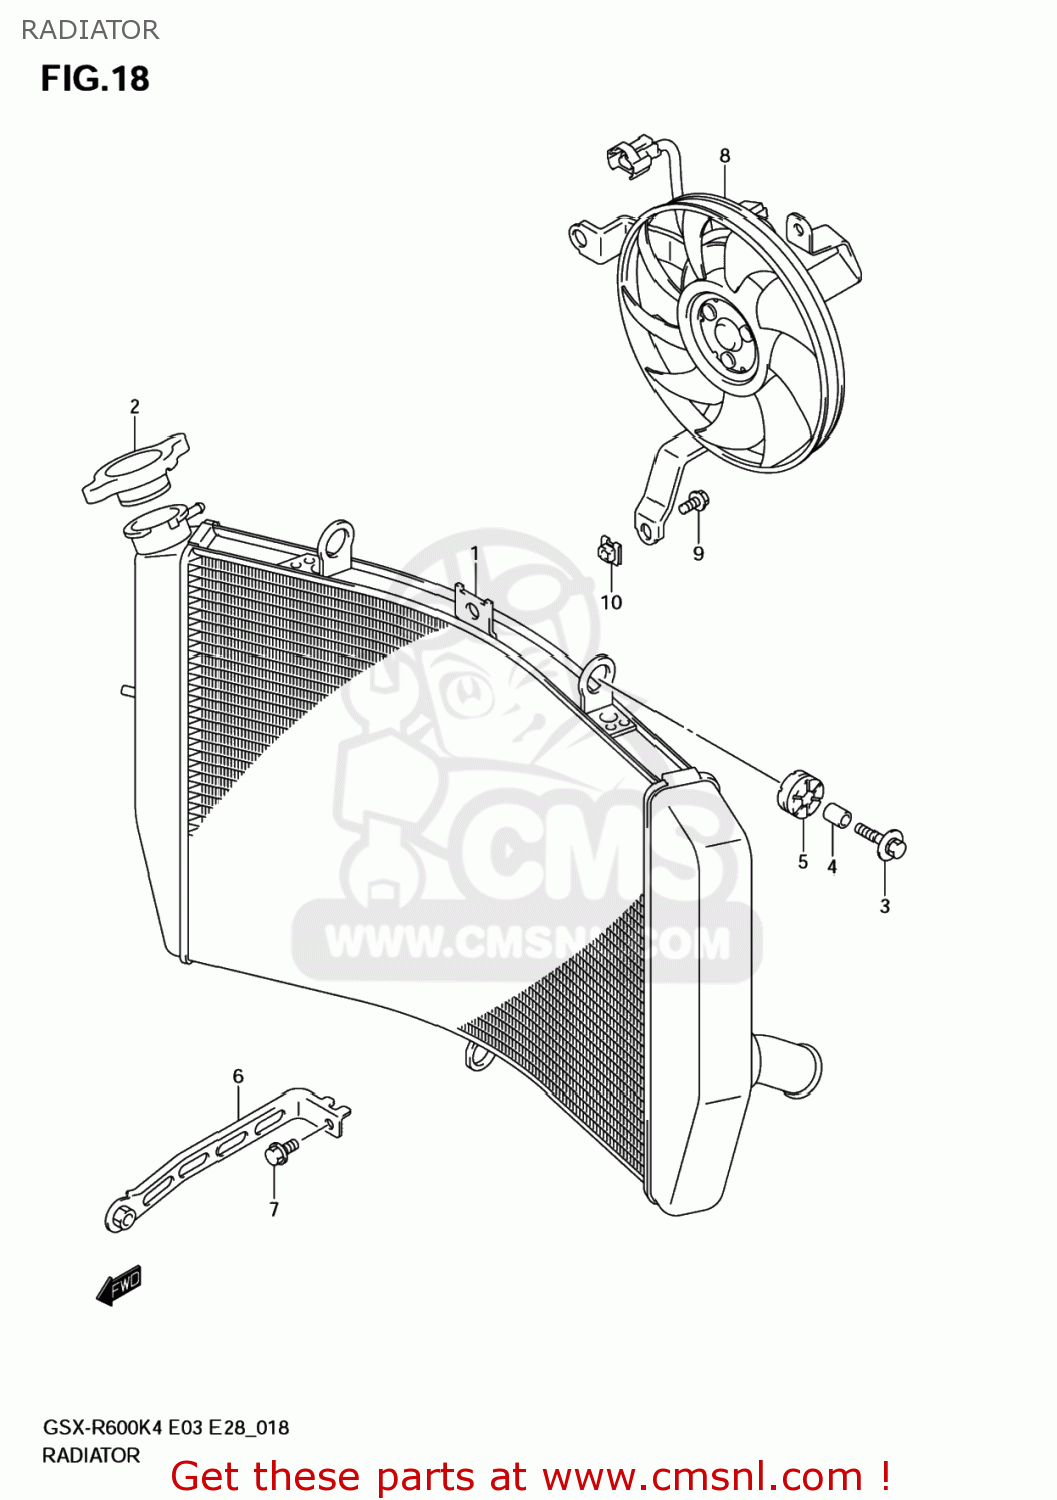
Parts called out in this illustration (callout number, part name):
1	RADIATOR ASSY,WATER
2	CAP COMP,RADIATOR
3	BOLT(6X25)
4	SPACER(6.5X10X12)
5	CUSHION
6	BRACKET,RADIATOR
7	BOLT
8	FAN ASSY,RADIATOR
9	BOLT,FAN ASSY
10	NUT,FAN ASSY
